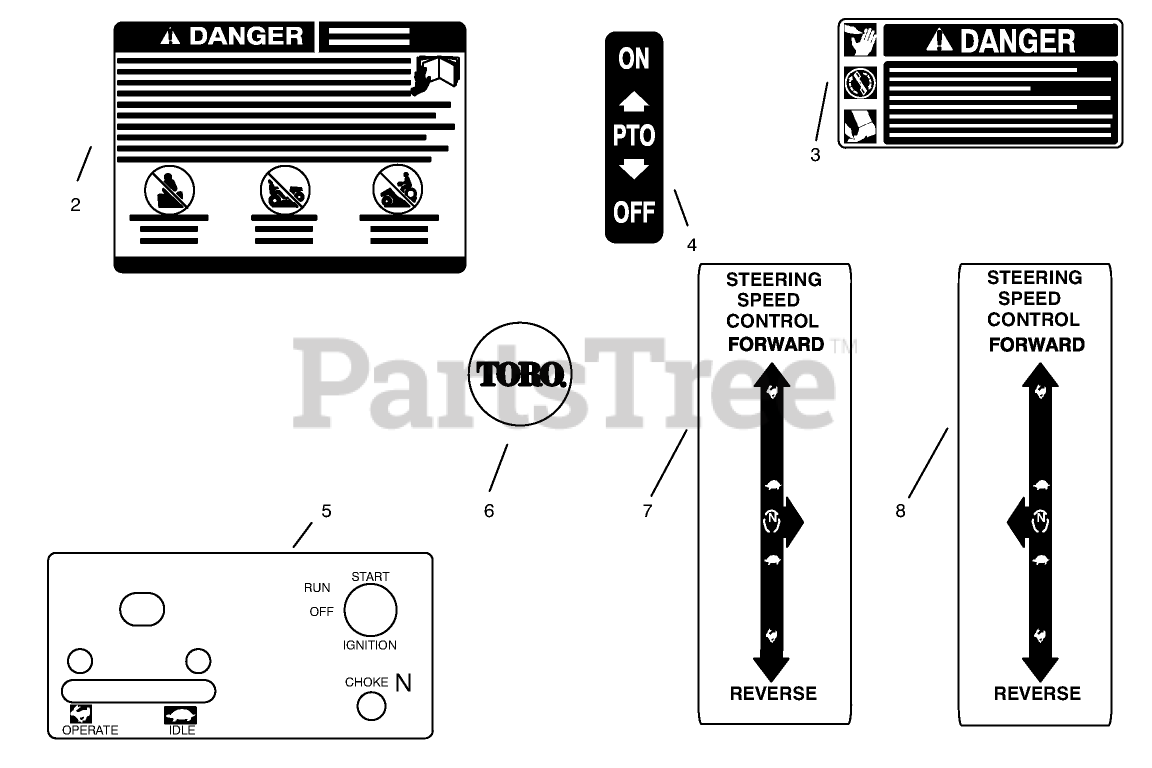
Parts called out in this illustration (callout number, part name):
2	DECAL-DANGER
3	DECAL-DANGER
4	DECAL-PTO
5	DECAL-CONTROL
6	NAME-PLATE TORO LOGO
7	DECAL-LH STRG SPD CONT
8	DECAL-RH STRG SPD CONT
